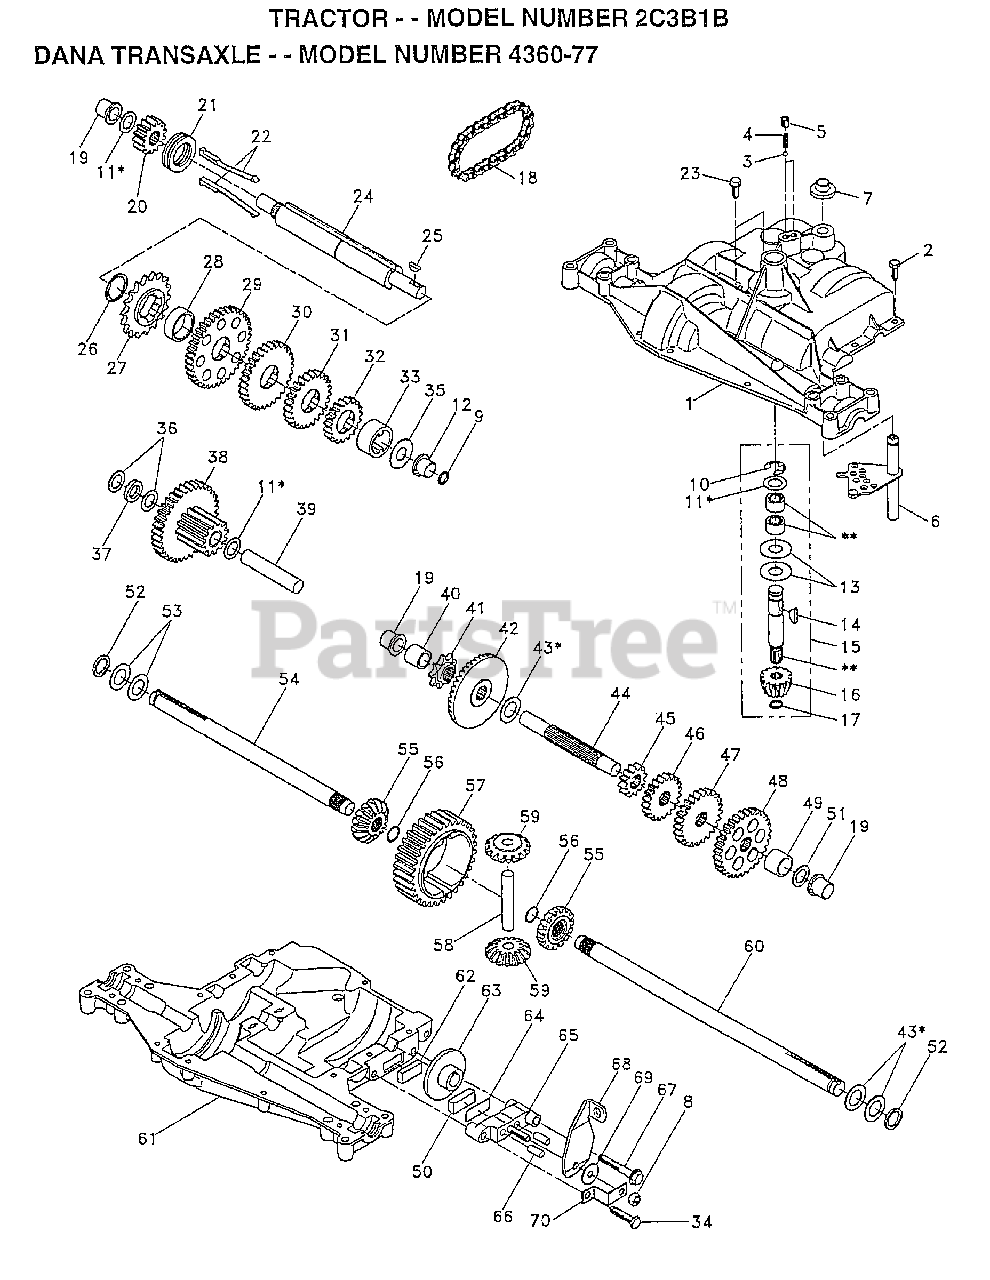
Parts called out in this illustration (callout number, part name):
1	HOUSING UPPER TRN
4	"SPRING, DETENT LT"
5	"SCREW, SET LT"
6	KIT SHIFTER ASM
7	SHIFTER BOOT
8	NUT.LOCK.5/16-24
9	SEAL OIL DANA5416
11	ASM KIT SHIM 4689
13	WASHER T
14	KEY WOODRUFF-DANA
15	AS KIT INPUT SHFT
16	PINION 14T T
17	"RING,RETAINING LT"
18	"CHAIN,24 PTCH LT"
19	BEARING.FLNG.5510
20	GEAR SPUR 14 TTH
21	COLLAR CLUTCH
22	ASM KIT CLTCH KEY
23	SCREW TAP W/SEAL
24	SHAFT INTERM DANA
25	WOODRUFF KEY
26	"RING,RETAINING LT"
27	SPROCKET 18T T
28	SPACER YT
29	GEAR SPUR 37 TTH
31	GEAR 25T LT
32	SPUR GEAR 19T
33	SPACER
34	"SCREW, TAPPING LT"
35	"WASHER, PLAIN LT"
36	WASHER 025
37	SPACER
38	ASSM GEAR COMB
39	SHAFT IDLER
40	SPACER T
41	SPROCKET 9T LT
43	ASM KIT SHIM
44	SHAFT T
45	GEAR SPUR 12 TTH
47	"GEAR, SPUR 25T LT"
48	"GEAR, SPUR 31T LT"
50	PUCK T
51	WASHER 060
52	NEOPRENE WASHER
53	WASHER 031
55	GEAR 15T T
56	"RING,RETAINING LT"
58	SHAFT T
59	GEAR 1ST T
61	HOUSING LOWER TNS
62	PUCK T
63	BRAKE DISC. T
64	SPACER LT
66	PIN T
69	WASHER LT
